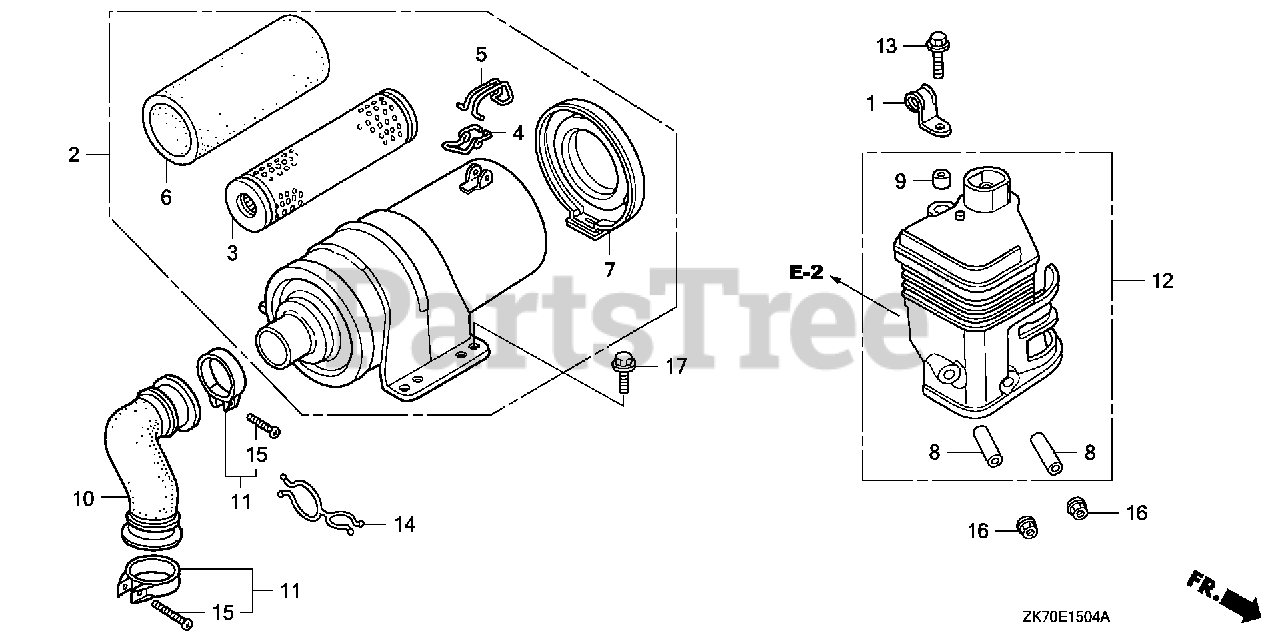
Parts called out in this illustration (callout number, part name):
1	CLIP B, TUBE
2	AIR CLEANER ASSY.
3	ELEMENT, AIR CLEANER
4	CLIP A, WIRE
5	CLIP B, WIRE
6	FILTER (OUTER)
7	COVER, AIR CLEANER
8	COLLAR, AIR CLEANER
9	COLLAR B, AIR CLEANER
10	TUBE, AIR CLEANER CONNECTING
11	BAND, AIR CLEANER CONNECTING TUBE
12	ELBOW, AIR CLEANER
13	BOLT, FLANGE (6X20)
15	SCREW, PAN (4X20)
16	NUT, FLANGE (6MM)
17	BOLT, FLANGE (6X16)
